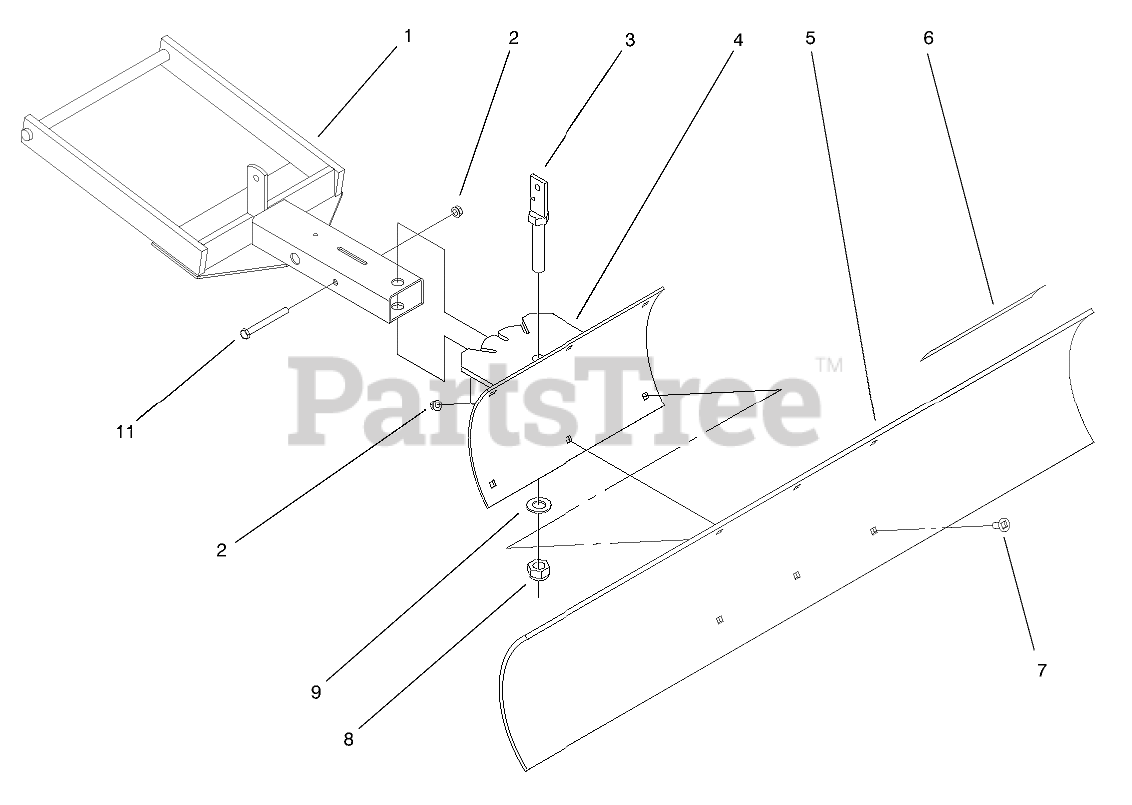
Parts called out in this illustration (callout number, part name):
1	Frame ASM
2	NUT-LOCK, NI
3	Wa-Scrw
4	ASS'Y-QUADRANT
5	BLADE/DECAL ASM
6	DECAL-ATTACHMENT
7	BOLT-CARR
8	NUT-LOCK, NI
9	WASHER-FLAT
11	SCREW-HH
